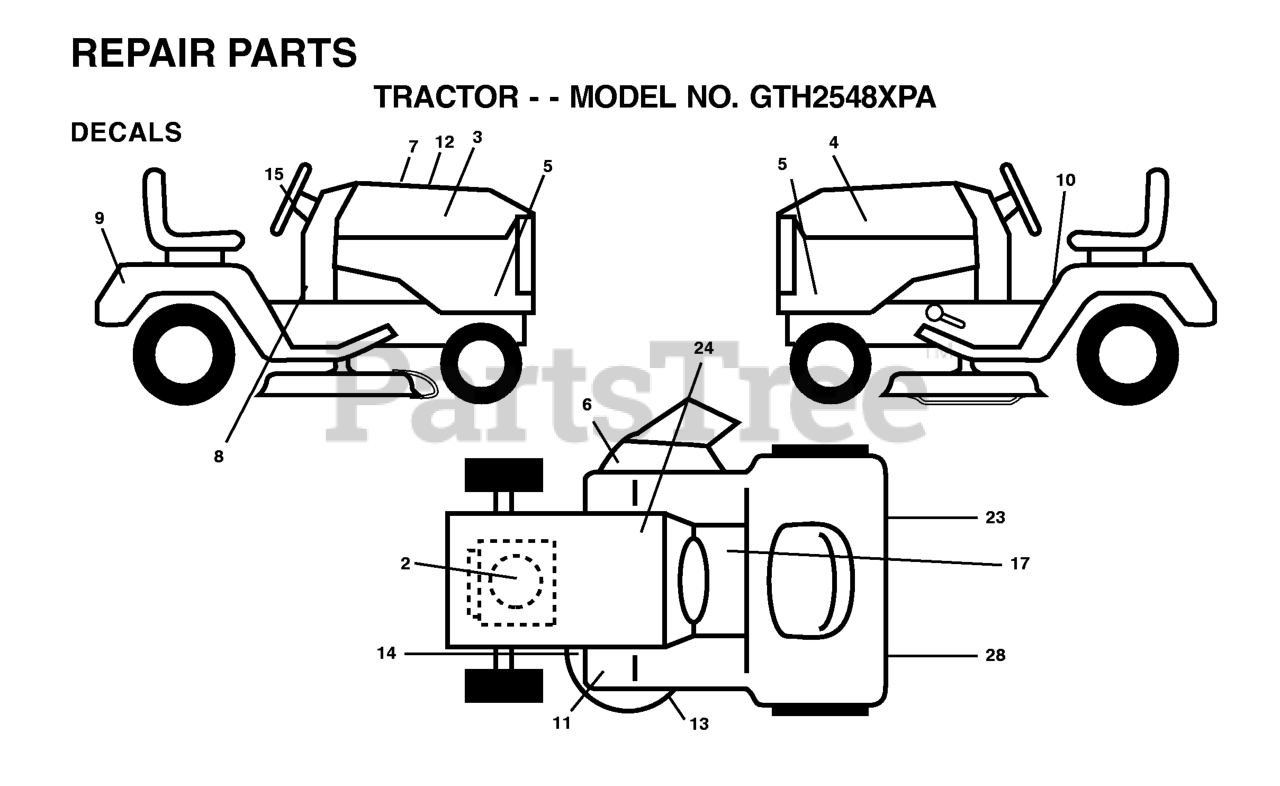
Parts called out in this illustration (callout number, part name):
2	DECAL.ENG.25HP.KAWA.HSQV.XP
3	RH HOOD DECAL
4	LH HOOD DECAL
5	DECAL HOOD SIDES
6	DECAL.WARN.KEEP.HAND.AWAY
8	DECAL, DASH
9	DECAL, FENDER
10	DECAL FENDER DANGER
11	DECAL, FOOTREST
13	DECAL V-BELT SCHEMATIC
14	DECAL CLUTCH/BRAKE
15	DECAL.WHEEL.STEERING.HUSQ.PERM
17	DECAL PARK BRAKE
23	REFLECTOR, RH
24	DECAL BTRY SYMBOLS
27	DECAL.BYPASS.FENDER.CRD.LT.YT
28	REFLECTOR, LH
